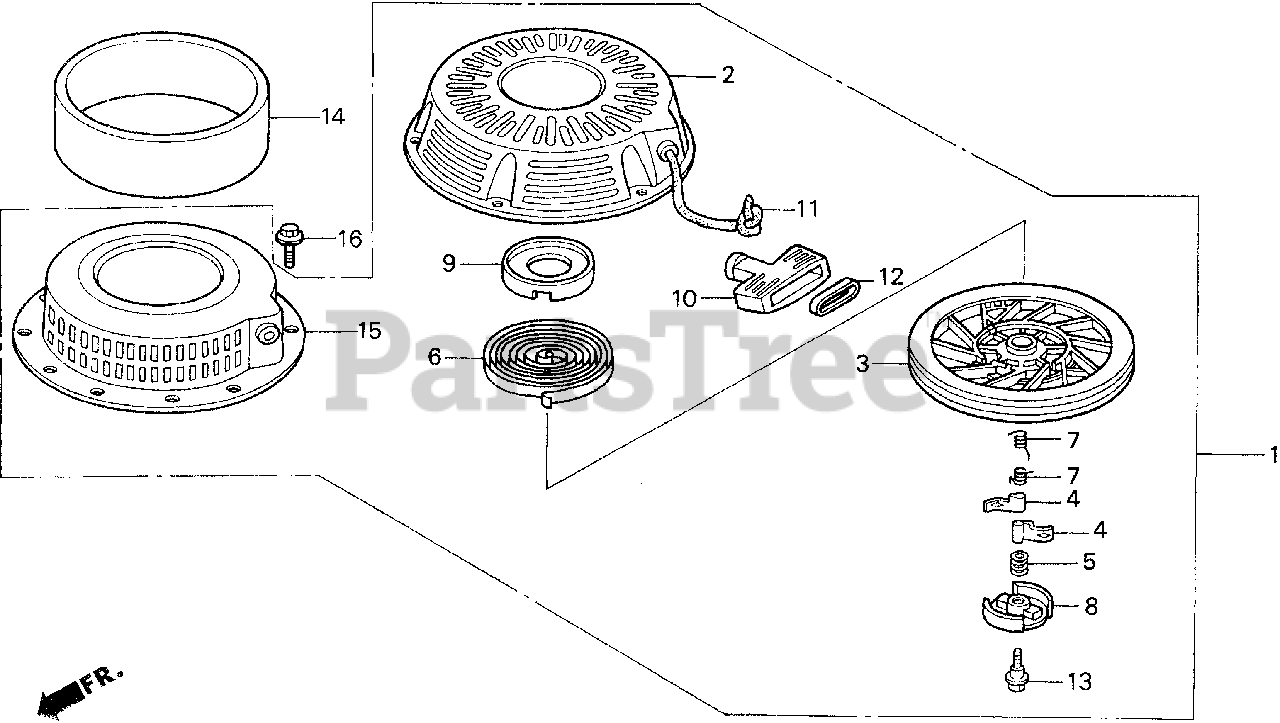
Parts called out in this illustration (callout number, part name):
1	STARTER ASSY., RECOIL *R8* (BRIGHT RED)
2	CASE COMP., RECOIL STARTER *R8* (BRIGHT RED)
3	PULLEY, RECOIL STARTER
4	RATCHET, STARTER
5	SPRING, FRICTION
6	SPRING, STARTER RETURN
7	SPRING, RATCHET
8	RETAINER, SPRING
9	HOLDER, SPRING
10	GRIP, STARTER
11	ROPE, RECOIL STARTER (N/A: USE P/N 08560-ZG921-11)
12	GRIP, REINFORCEMENT
13	SCREW, CENTER
